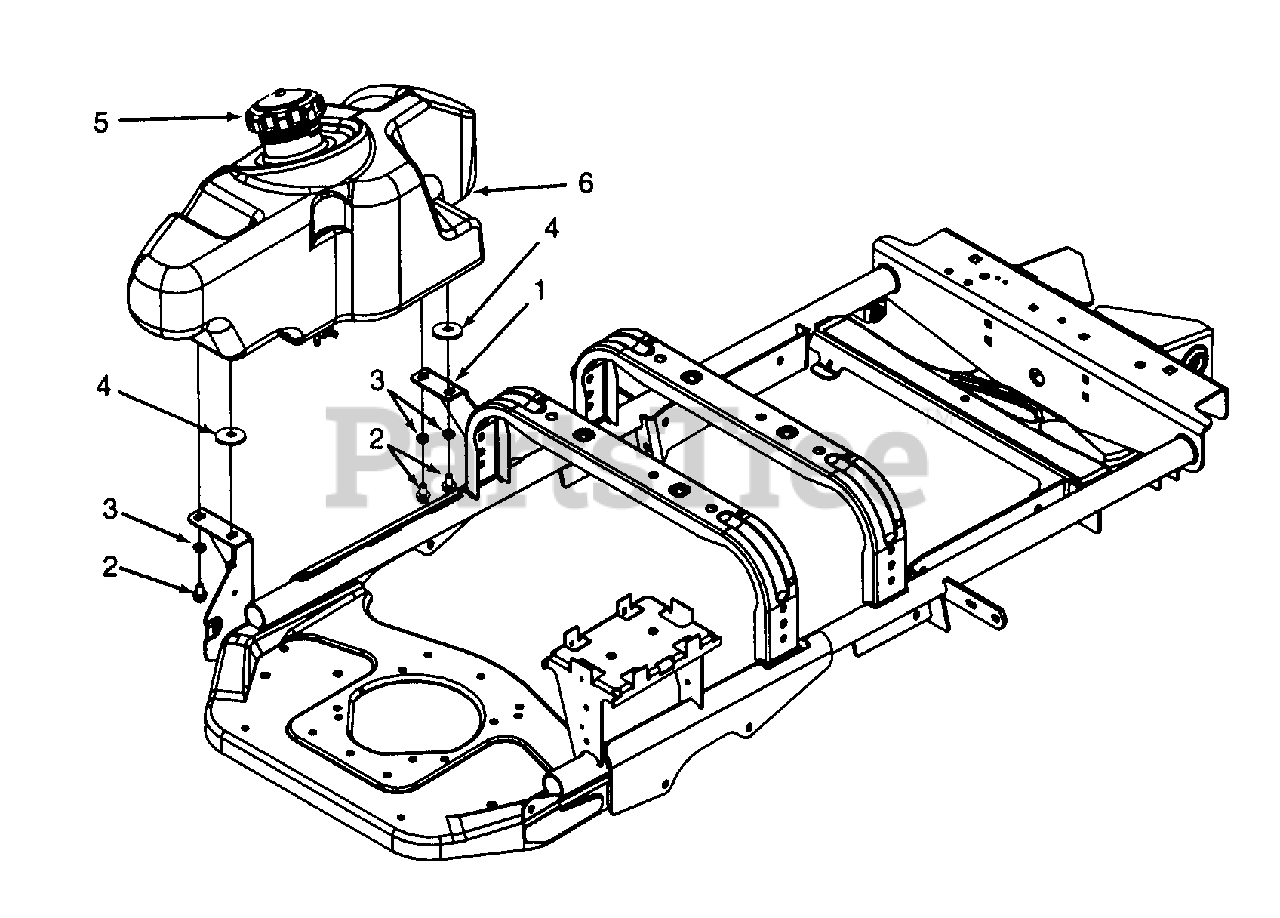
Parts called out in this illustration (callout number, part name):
3	Lock Washer 3/8
4	Flat Washer .390 ID x 1.5 OD
5	Fuel Cap
